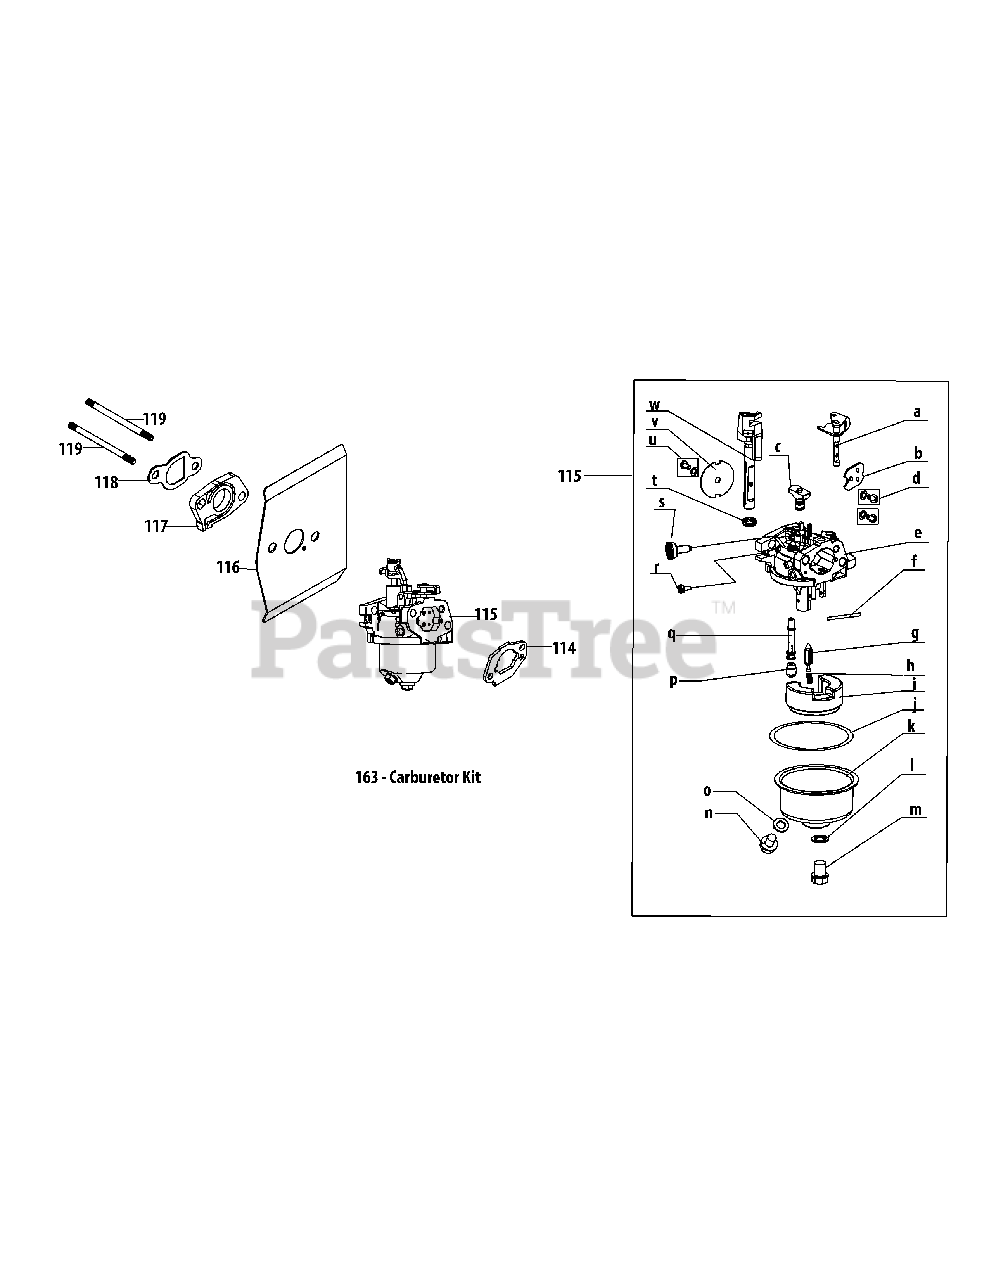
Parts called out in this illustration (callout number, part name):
114	Air Filter Base Gasket
115	Carburetor Assembly
116	Carburetor Gasket
117	Carburetor Insulator
118	Carburetor Insulator Gasket
119	Carb Stud M6×87
163	Carburetor Kit
